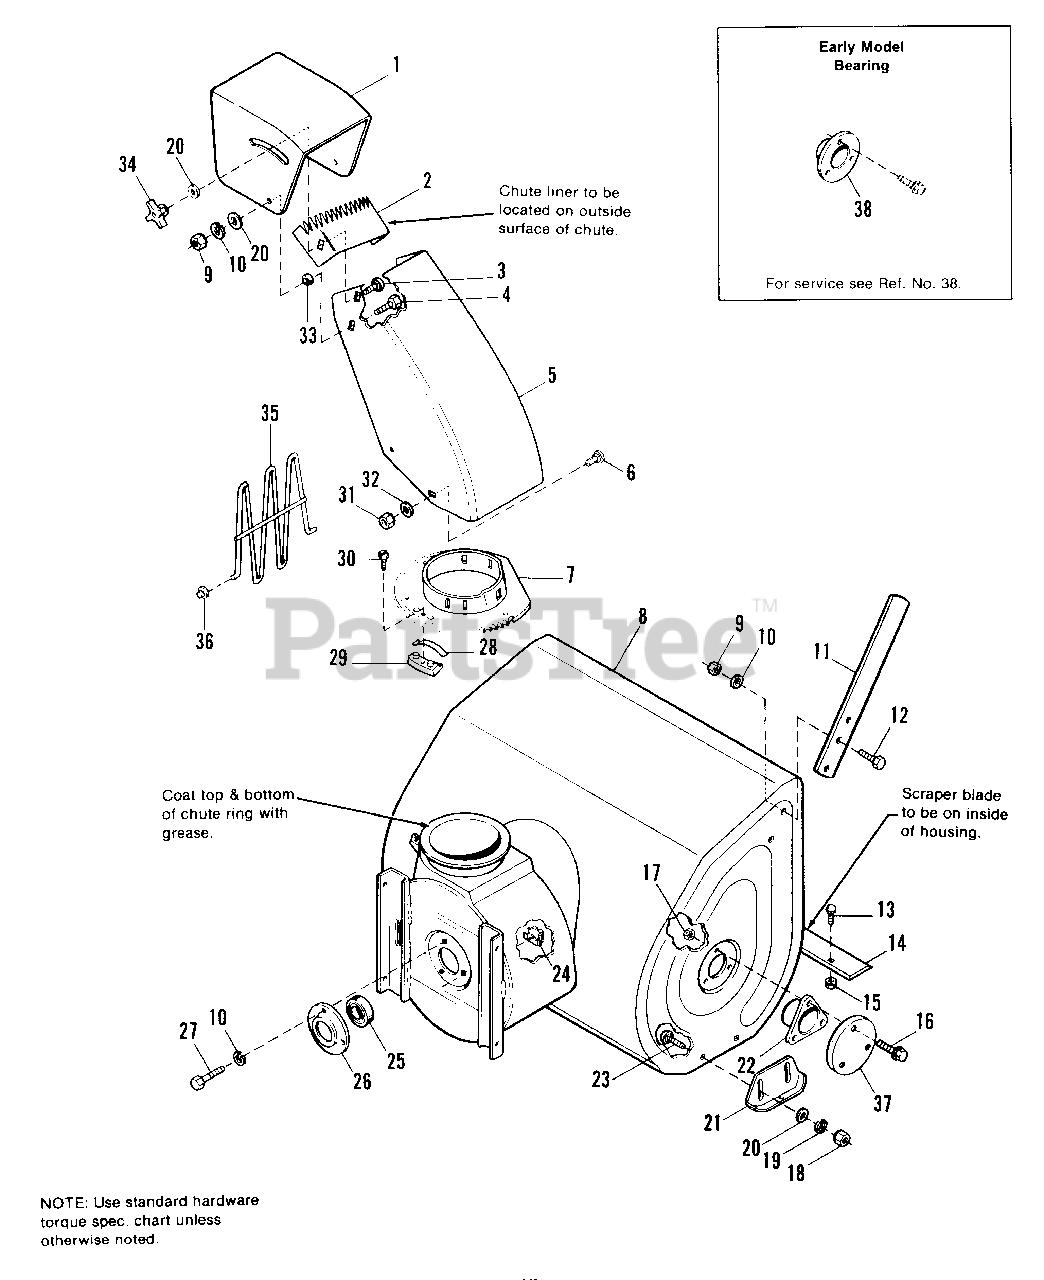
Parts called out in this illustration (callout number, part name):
1	DEFLECTOR ASSY.
2	LINER, Chute
3	BOLT, Carriage, 5/16-18 x 7/8
4	SCREW, Truss Phil Hd., 5/16-18 x 3/4
5	CHUTE
6	BOLT, Carriage, 1/4-20 x 5/8
7	GEAR, Chute
8	HOUSING ASSY., Auger, 60 cm (24")(Used on all models except Mfg. No.1691377 & 1671378)
8	HOUSING ASSY., Auger, 70 cm (28")(Used on Mfg. No. 1691377 & 1691378 only)
9	NUT, 5/16-18 (Qty. 6 on 1691377 & 1691378)
10	LOCKWASHER, 5/16 (Qty. 9 on 1691377 & 1691378)
11	CUTTER, Drift (1691377 & 1691378 only)
12	CAPSCREW, Hex Hd ., 5/16-18 x 3/4 (1691377 & 1691378 only)
13	BOLT, Carriage, 5/16-18 x 5/8
14	BLADE, Scraper, 60 cm (24")
14	BLADE, Scraper, 70 cm (28")
15	LOCKNUT, Flange, 5/16-18
16	CAPSCREW, Hex Flange Whizlock 5/16-18 x 7/8
17	NUT, Hex, Center Lock, 5/16-18
18	NUT, Hex, 3/8-16
19	LOCKWASHER, 3/8
20	WASHER, Flat, 5/16
22	BEARING, Auger
23	BOLT, Carriage, 3/8-16 x 3/4
24	NUT, Retainer, 5/16-18
25	BEARING, Ball
26	RETAINER, Bearing
27	CAPSCREW, Hex Hd., 5/16-18 x 5/8
29	HOLD DOWN, Chute
30	SCREW, Plastite, #10
31	LOCKNUT,Nylon, 1/4-20
32	WASHER, Flat, 1/4
34	KNOB, 4 Arm w/5/16-18 Thd. Insert
35	GUARD, Chute
36	PUSH NUT
37	CAP, Bearing
38	BEARING KIT, Auger
